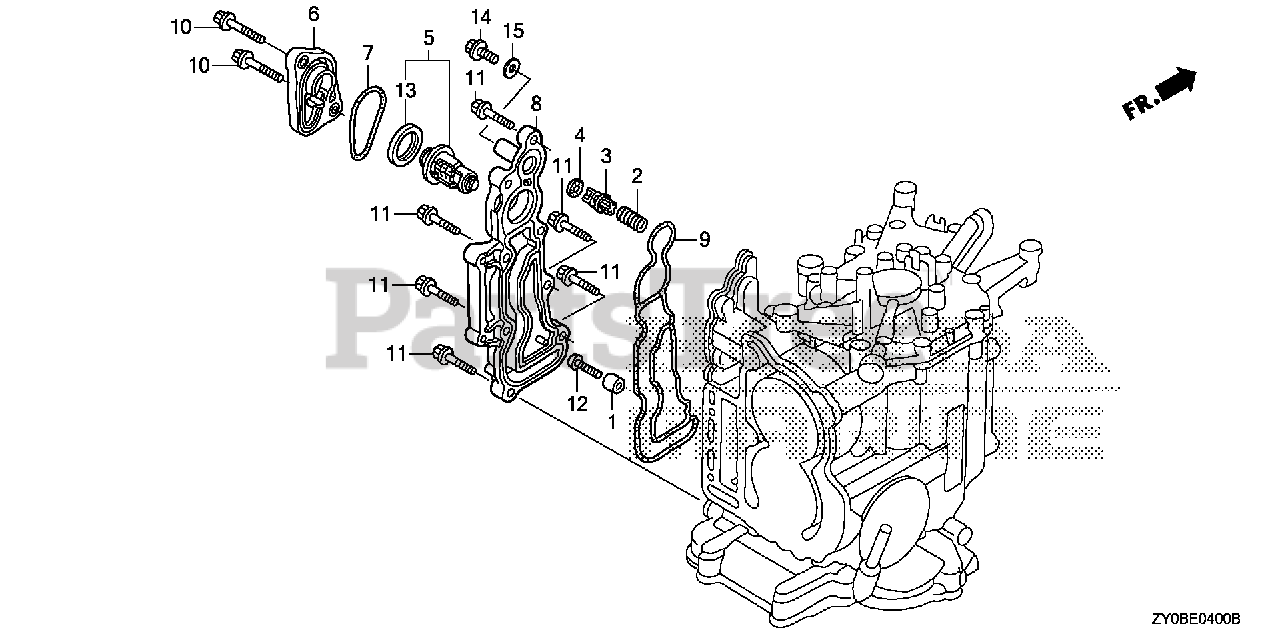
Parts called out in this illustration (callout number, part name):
1	METAL, ANODE
2	SPRING, FLUSH VALVE
3	VALVE, FLASH
4	GASKET, FLASH VALVE
5	THERMOSTAT ASSY.
6	COVER, THERMOSTAT
7	O-RING, THERMOSTAT COVER
8	COVER, WATER JACKET
9	GASKET, EX. WATER JACKET COVER
10	BOLT, FLANGE (6X36) (CT200)
11	BOLT, FLANGE (6X22) (CT200)
12	SCREW, PAN (5X20)
13	RUBBER, RING
14	BOLT, SPECIAL (8MM)
15	GASKET (8MM)
